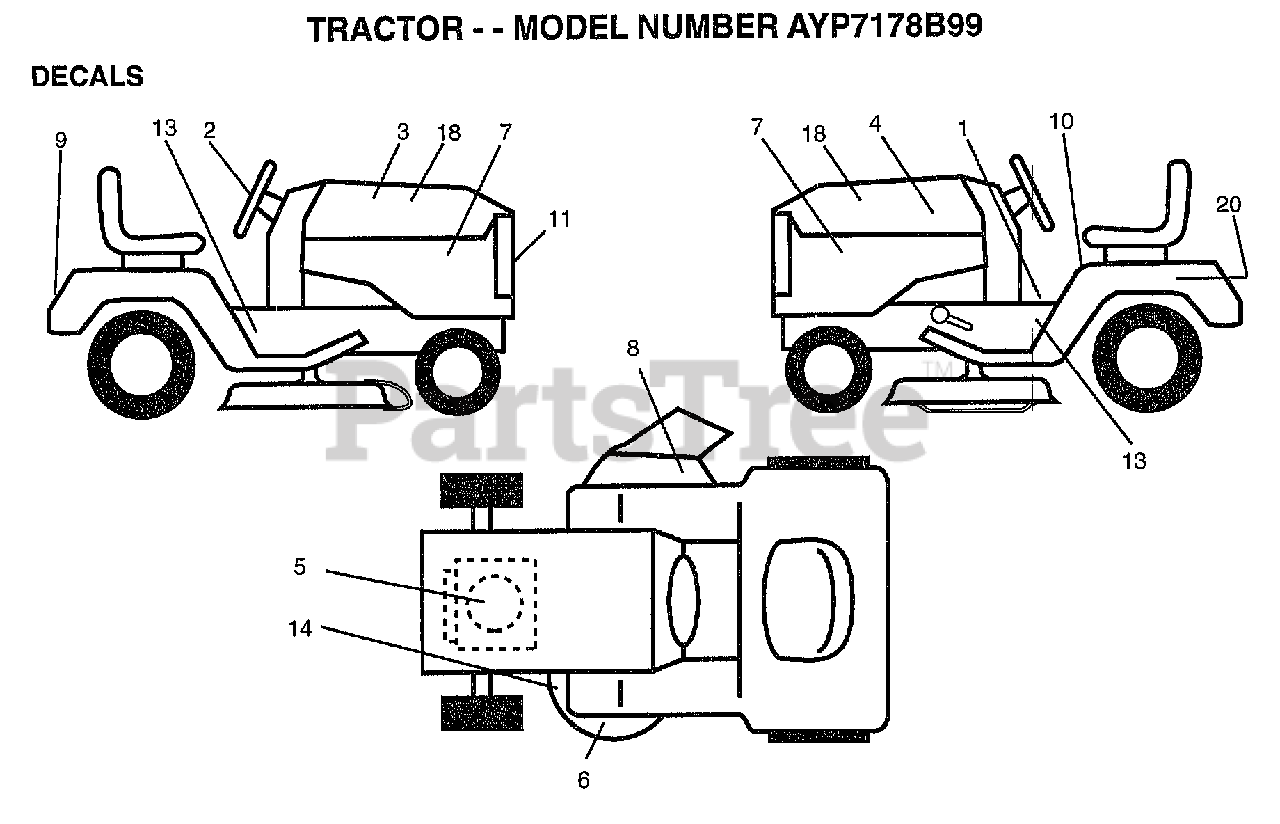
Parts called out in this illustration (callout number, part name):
1	"DECAL-DASH,OPER"
2	DECAL STEER WHL
3	DECAL HOOD RH
4	DECAL HOOD LH
5	DECAL, HP ENGINE
6	DECAL DECK MULCH
7	DECAL.SIDE PANEL
8	DECAL DECK WIZ +
10	"DECAL DANGER,FEND"
11	DECAL.LENS.WIZARD
13	DECAL CHASSIS WIZ
14	"DECAL-SCHEM,BELT"
18	NAMEPLATE.HD.WIZA
20	DECAL.BATRY.3-3908
